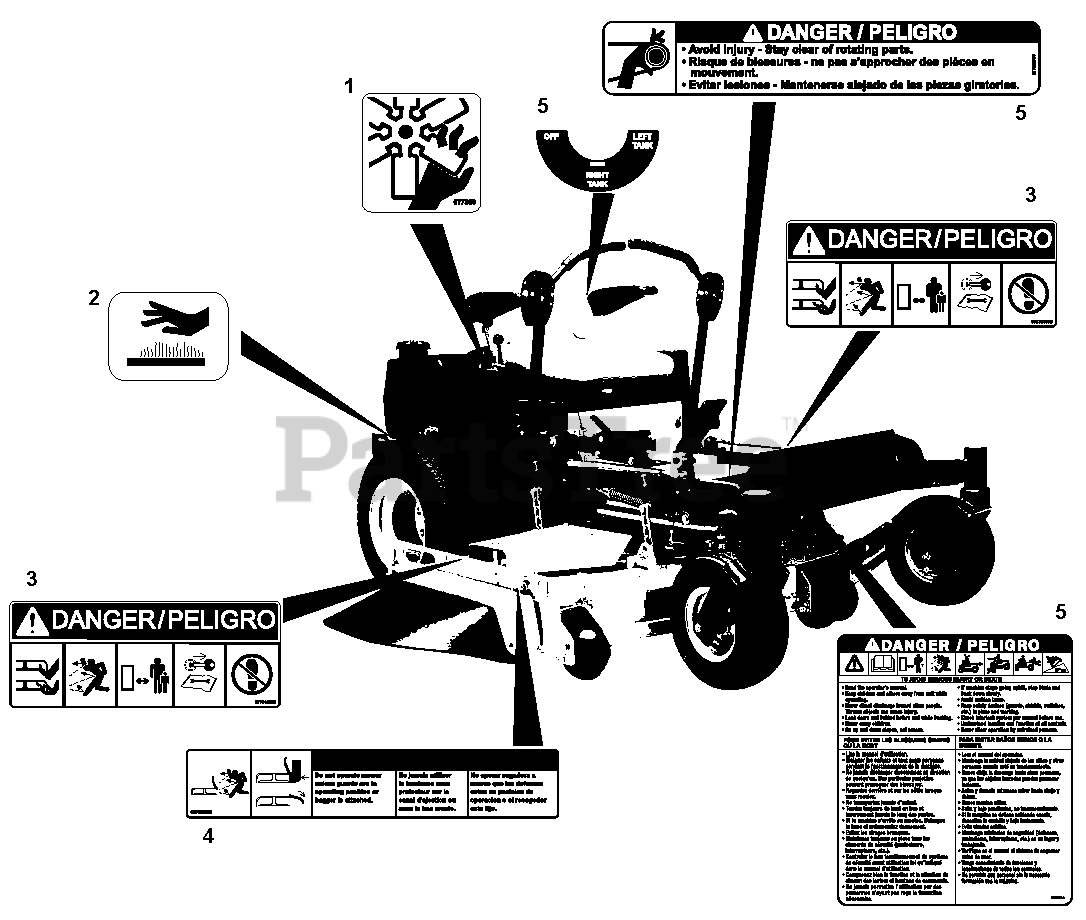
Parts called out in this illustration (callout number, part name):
1	Decal, Danger Fan
2	Decal, Hot Surface
3	Decal, Mower Pan Head Danger
4	Decal, Warning
5	Set, Decal Common Danger/Fuel
